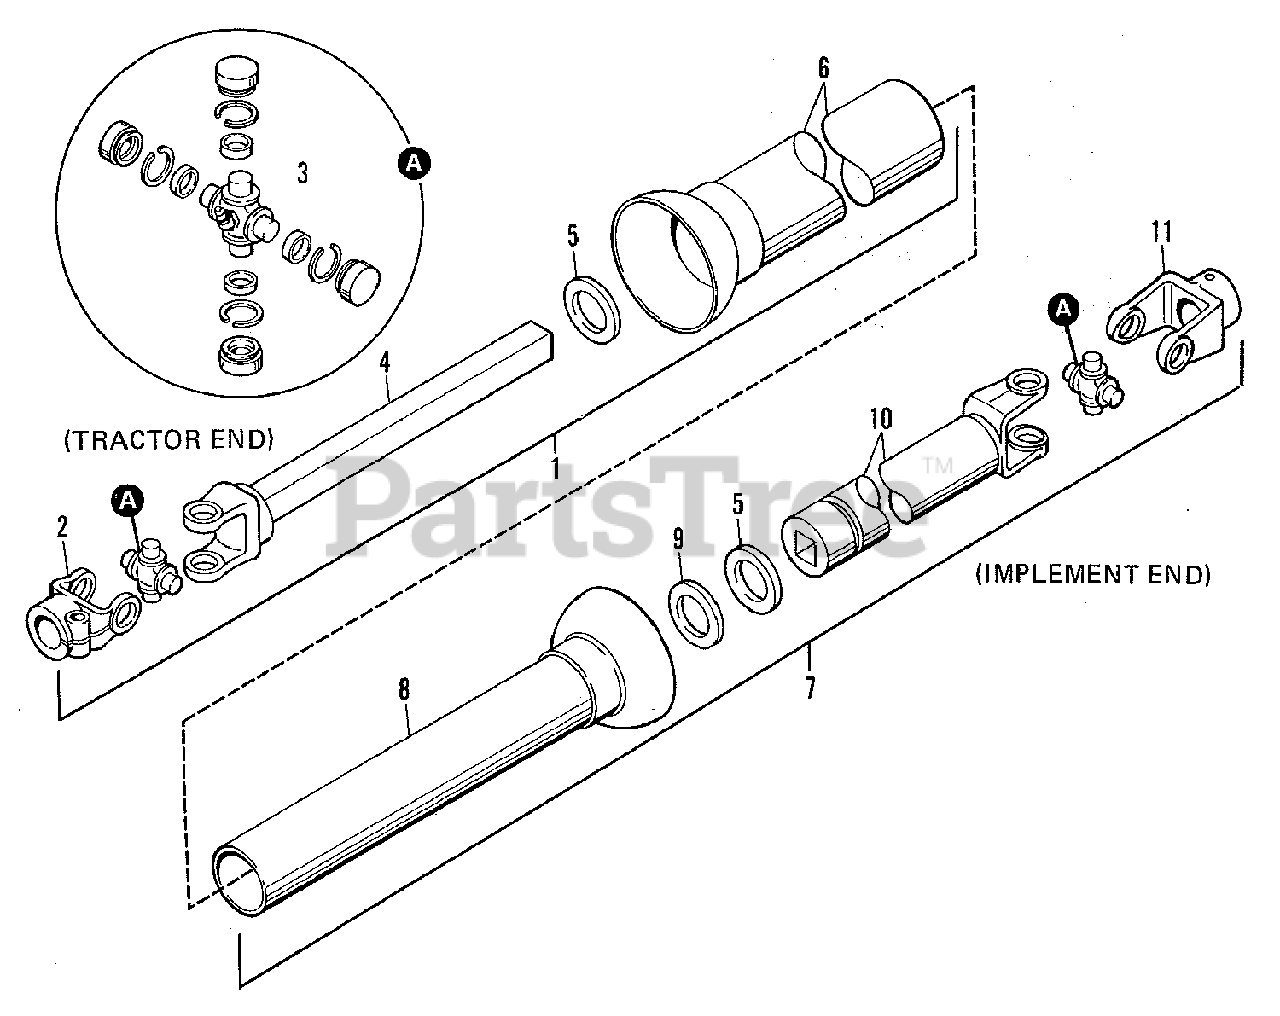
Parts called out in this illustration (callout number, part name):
1	PTO ASSEMBLY, Tractor End
2	YOKE, Tractor End
3	U-JOINT KIT
3	FITTING, Lube, Special Short, 1/4 x 65 Degrees
4	SHAFT & YOKE ASSEMBLY
6	SHIELD, Outer
7	PTO ASSEMBLY, Implement End
8	SHIELD, Inner
9	BEARING, Nylon
10	TUBE & YOKE ASSEMBLY
11	YOKE, Implement End (Type l)
11	YOKE, Implement End (Type ll)
11	CAPSCREW, Socket Head, 3/8NC x 2, Gr. 8
